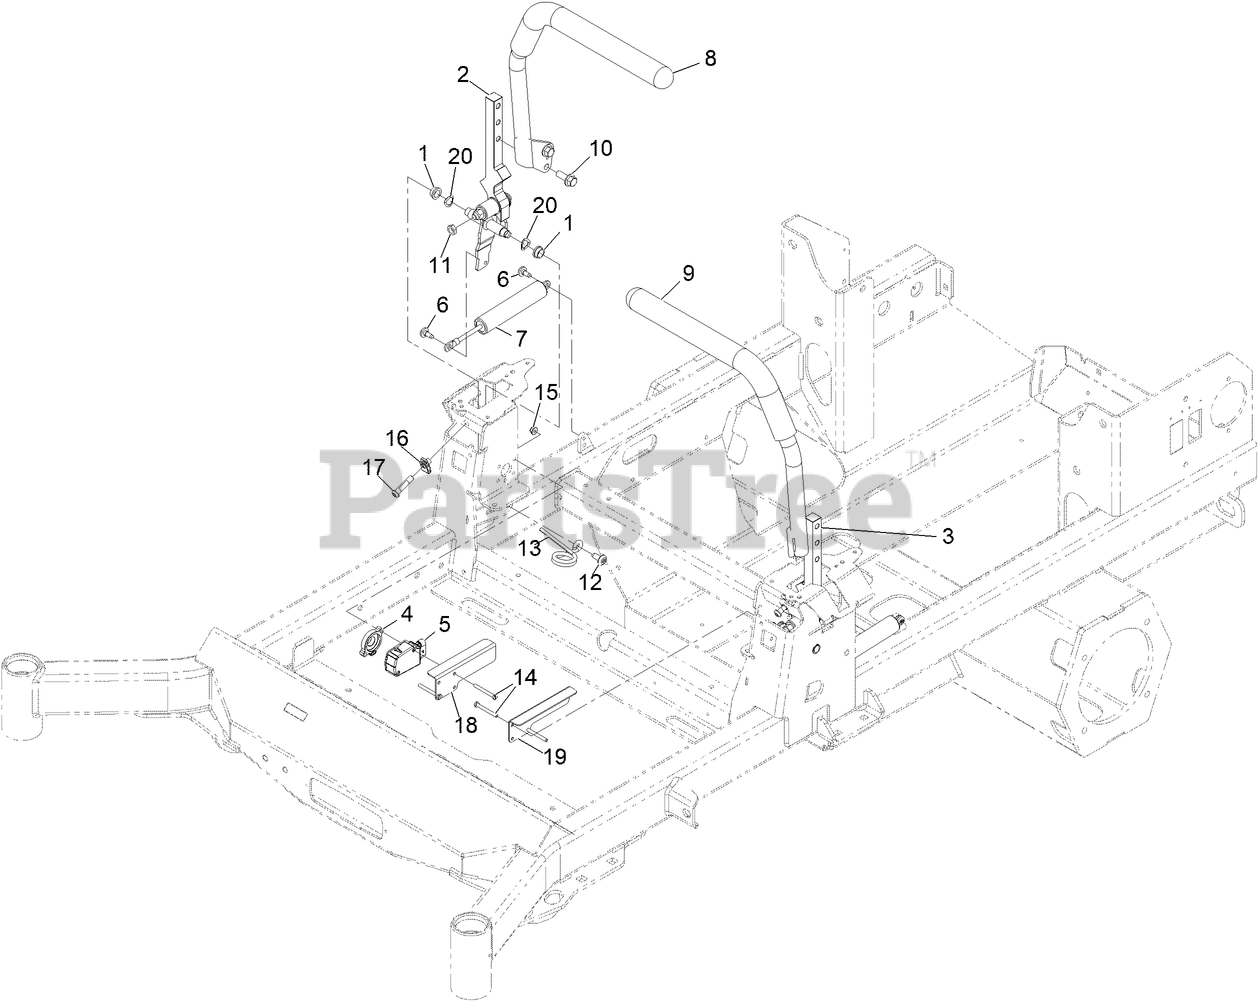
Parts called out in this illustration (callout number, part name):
1	BUSHING-FLANGE
2	RH MOTION CONTROL ASM
3	LH MOTION CONTROL ASM
4	SPACER-SENSOR
5	SENSOR-POSITION
6	SCREW-SHOULDER
7	DAMPER-NON CAVITATING
8	ASM-HANDLE RH, BLACK
9	ASM-HANDLE LH, BLACK
10	SCREW-HHF
11	NUT-JAM
13	SPRING-TORSION
14	SCREW-SHH
15	Nut-Hex Flange
17	SCREW-HSBH
18	PLATE-COVER, SENSOR RH
19	PLATE-COVER, SENSOR LH
20	WASHER-SPRING
